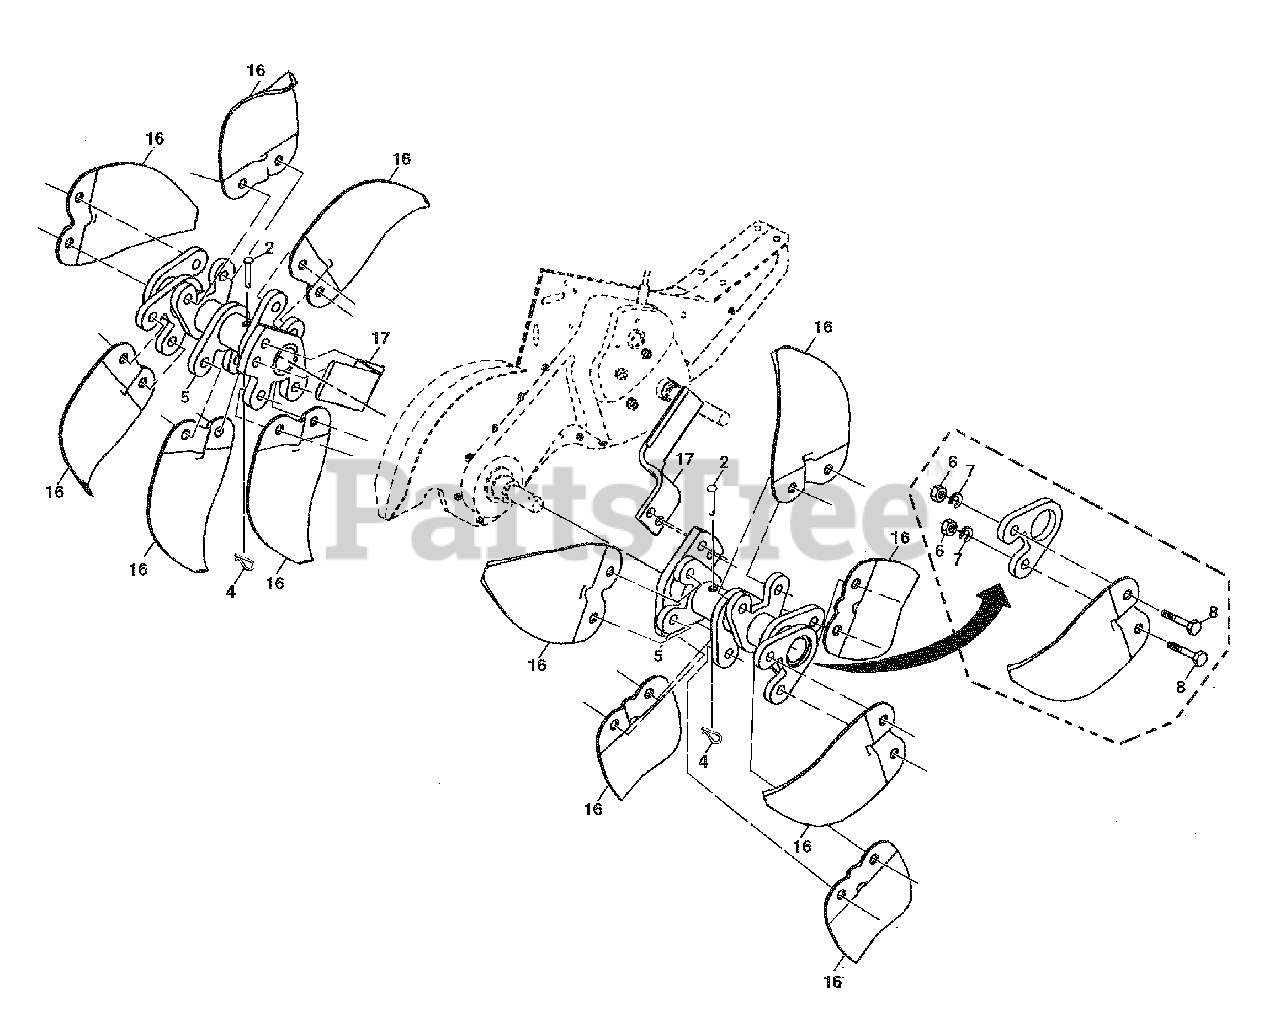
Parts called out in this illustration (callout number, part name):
2	Pin, Shear
4	Clip, Hairpin
5	Hub Assembly
6	Nut, Hex 3/8-24
7	Washer, Lock 3/8
8	Bolt, Hex 3/8-24 x 1
16	Tine, Spade
17	Tine, Cleaning
